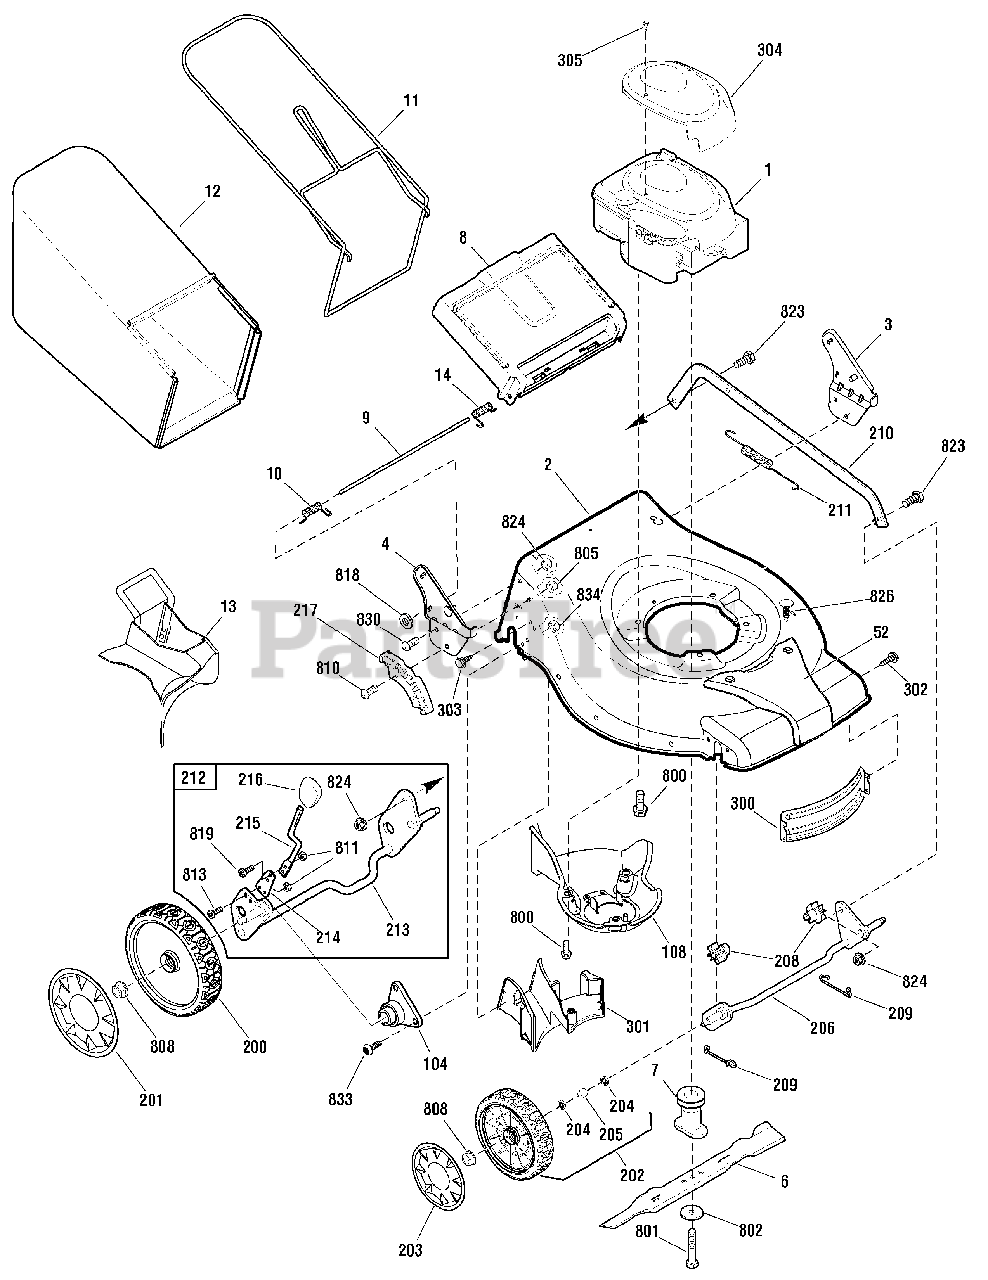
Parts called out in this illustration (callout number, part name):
1	* ENGINE, B&S 550 Series EU
2	MOWER HOUSING
3	BRACKET ASSEMBLY, Left Handle
4	BRACKET ASSEMBLY, Right Handle
6	BLADE, 16"
7	BLADE ADAPTER ASSEMBLY
8	DOOR, Rear
9	ROD, Rear Door
10	SPRING, Torsion Rear Door, Right
11	FRAME ASSEMBLY
12	BAG ASSEMBLY
13	MULCH PLUG
14	SPRING, Torsion Rear Door, Left
52	HOUSING COVER, Front
104	SLEEVE ASSEMBLY, Rear Axle
108	BELT COVER ASSEMBLY
200	WHEEL, Rear
201	HUBCAP, Rear
202	WHEEL, Front, Complete
203	HUBCAP, Front
204	WHEEL BEARING (Not Available)
205	SPACER (Not Available)
206	CROSSBAR ASSEMBLY, Front
208	BUSHING, Front Crossbar
209	SPRING, Clip Crossbar
210	LINK, Single Lever
211	SPRING, Extension
212	CROSSBAR ASSEMBLY, Rear (Not Available)
213	REAR CROSSBAR
214	SPRING, Adjuster
215	LEVER, Height Adjustment
216	KNOB, Adjuster
217	BRACKET, Height Adjuster
300	BAFFLE, Front
301	BAFFLE, Rear
302	SCREW, 1/4-20 x 1/2
303	SCREW, 1/4-15 x 5/8
304	SHROUD, With Label
305	SCREW, Pan Head
800	SCREW, Hex Head, 3/8-16 x 1
801	BOLT, Blade, 3/8-24 x 2
802	WASHER, Belleville
805	NUT, Nylock, M8 x 1-1/4
808	NUT, Flange, 3/8-16
810	BOLT, Hex Key Head
811	NUT, Nylock
813	SCREW, Torx Head, M5 x .8 x 14mm
818	PUSHNUT, 1/4
819	SCREW, Torx Head, M5 x .8 x 12.5mm
823	BOLT, Shoulder, 5/16-18 x 1
824	Nut, Flange, 5/16-18
826	SCREW, 1/4-20 x 7/8
830	SCREW , 5/16-18 x 3/4
833	SCREW, Torx, 1/4-20 x 5/8
834	NUT, Flange Lock, 1/4-20
